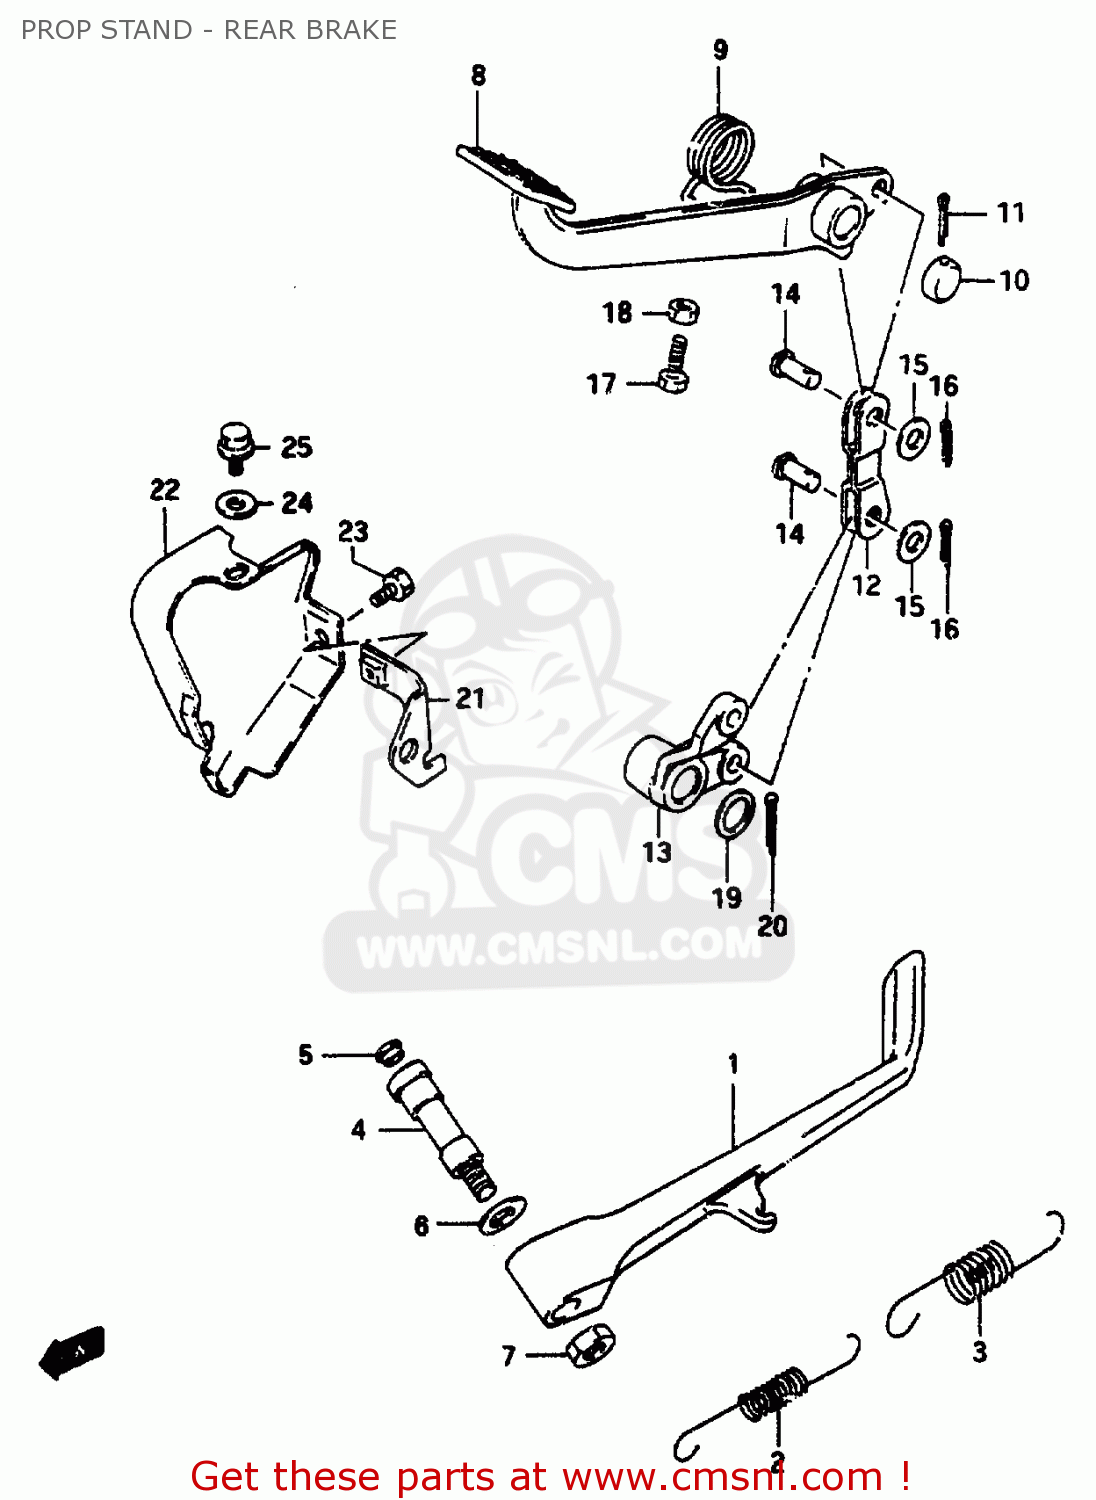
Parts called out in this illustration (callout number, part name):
1	STAND,PROP
2	SPRING
3	SPRING
4	BOLT,PROP STAND
5	CAP
6	THRUST WASHER
7	NUT
8	PEDAL,BRAKE
9	SPRING
10	CAP,BRAKE PEDAL
11	COTTER PIN
12	LINK COMP,BRAKE ROD NO
13	ARM,BRAKE PEDAL LINK
14	PIN
15	WASHER
16	PIN
17	BOLT
18	NUT
19	WASHER (16.2X22X1)
20	COTTER PIN
21	BRACKET COMP,BRAKE COVER
22	COVER,BRAKE
23	SCREW(6X10)
24	WASHER(6.5X15X1.0)
25	BOLT
